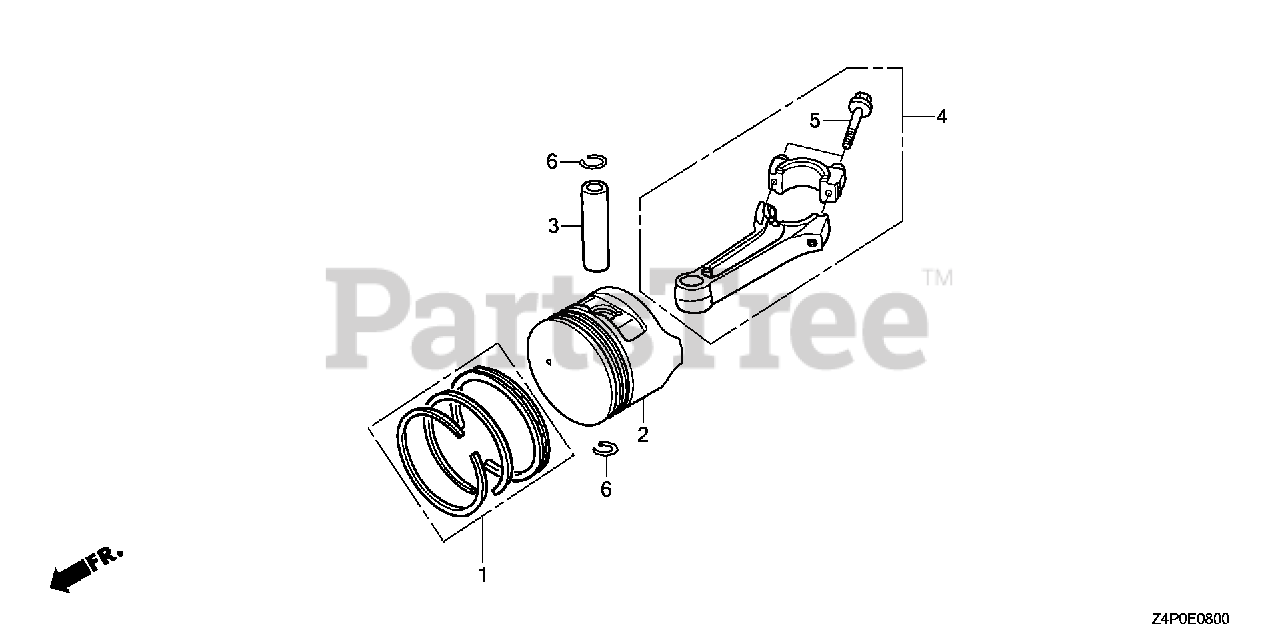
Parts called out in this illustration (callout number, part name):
1	RING SET, PISTON (STD) (TPR)
1	RING SET, PISTON (STD) (RIKEN)
1	RING SET, PISTON (0.25) (TPR)
1	RING SET, PISTON (0.25) (RIKEN)
1	RING SET, PISTON (0.50) (TPR)
1	RING SET, PISTON (0.50) (RIKEN)
1	RING SET, PISTON (0.75) (TPR)
1	RING SET, PISTON (0.75) (RIKEN)
2	PISTON (STD)
2	PISTON (0.25)
2	PISTON (0.50)
2	PISTON (0.75)
3	PIN, PISTON
4	ROD ASSY., CONNECTING (IDENT MARK Z)
4	ROD ASSY., CONNECTING
5	BOLT, CONNECTING ROD (IDENT MARK Z)
6	CLIP, PISTON PIN (18MM)
